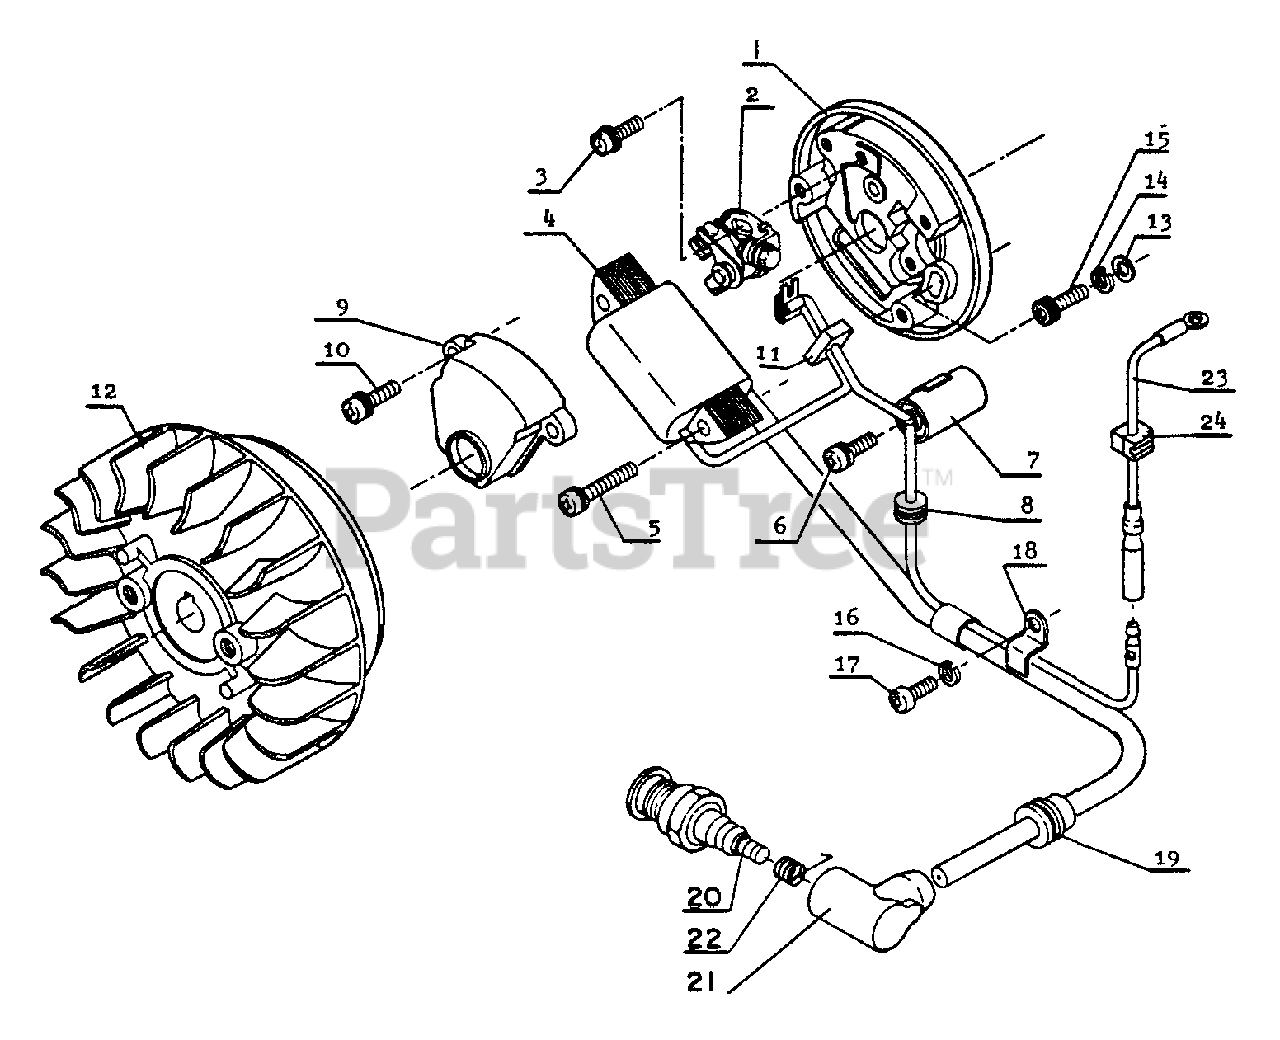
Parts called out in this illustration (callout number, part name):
1	PLATE, STATOR
2	CONTACT POINT SET
3	SCREW - 4X8
4	COIL, IGNITION
5	SCREW - 4X20
6	SCREW - 4X8
7	CONDENSER
8	GROMMET
9	COVER, BREAKER
10	SCREW - 4X10
11	GROMMET
12	FLYWHEEL
13	WASHER - 5
14	LOCKWASHER - 5
15	SCREW - 5X15
16	LOCKWASHER - 4
17	SCREW - 4X10
18	CLIP
20	SPARK PLUG -- BM-6A
21	CAP, SPARK PLUG
22	TERMINAL, SPARK PLUG CAP
23	LEAD - GROUND
24	GROMMET
